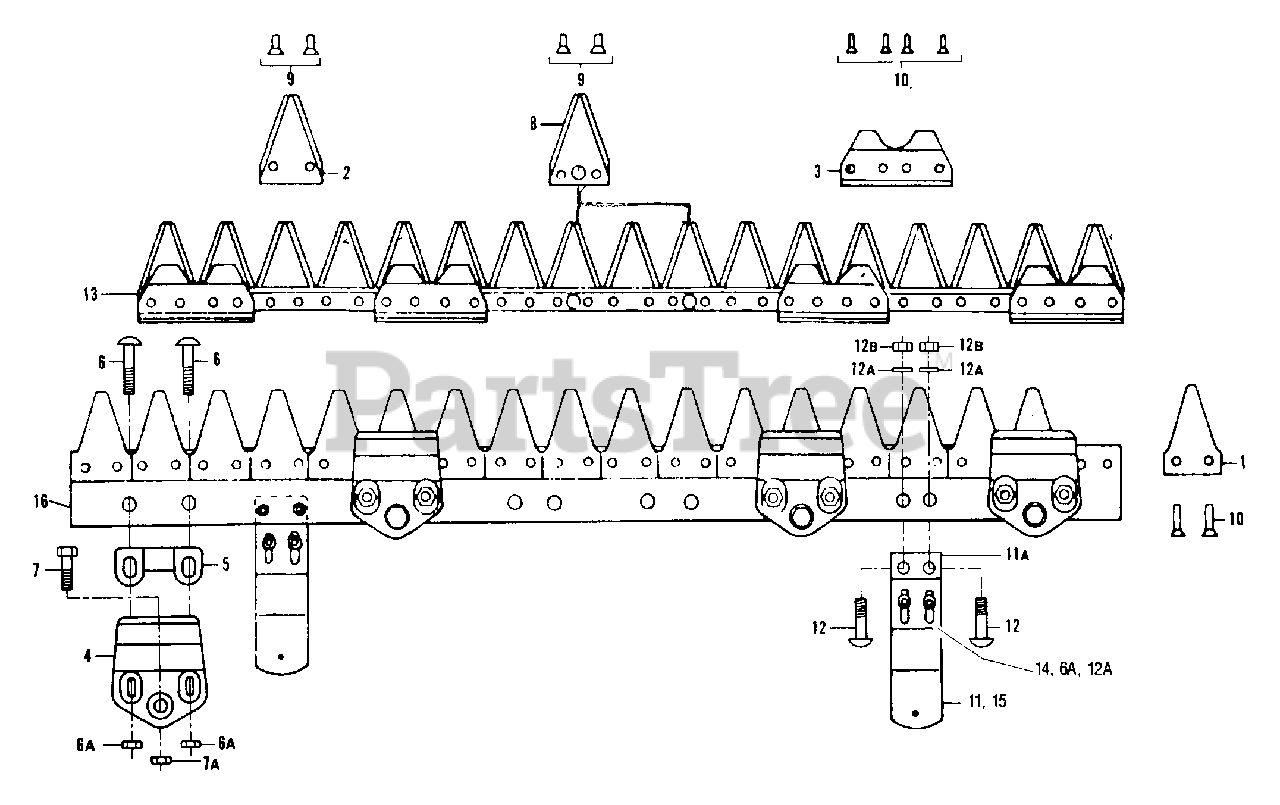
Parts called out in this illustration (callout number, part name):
1	Blade Section
2	Blade Section - 2 Holes
4	Blade Guide
6	Bolt M8 x 40 RH SQNK
6A	Nut
7	Bolt HHM8 x 30
8	Blade Sections - 3 Holes
9	Rivets CS90 5.3 x 14
10	Rivets CS90 5.3 x 16
11	Height Adjusters (Bottom Half)
11A	Height Adjusters (Top Half)
12	Bolt M8 x 30 RH SQNK
12A	Washer
13	Complete Cutter Blade Assembly
14	Screw M8 x 25 HH
15	Height Adjuster Assembly
16	Bar Ledger
